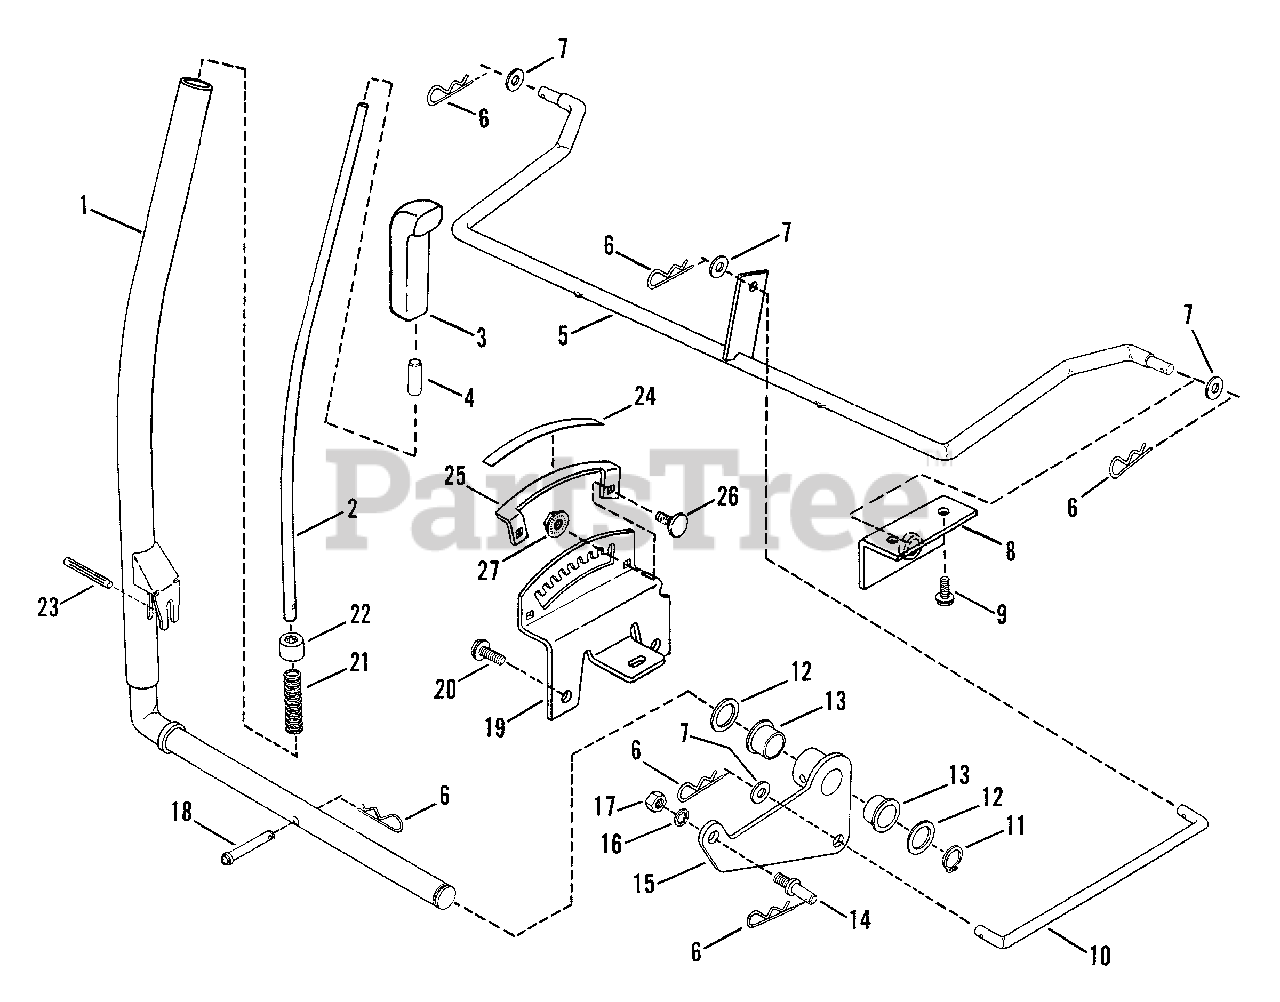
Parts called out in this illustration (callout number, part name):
1	ARM, Implement Lift Lever
2	ROD, Lift Lever
3	GRIP, Lift Lever
4	CAP, Lift Release
5	ARM, Rear Lift
6	PIN, Hair, 3/32 x 1 1/2"
7	WASHER, 3/8 SAE Flat
8	BRACKET, Hanger
9	SCREW, 5/16-18 x 5/8" H.W.H.S.T.
10	LIFT-ROD
11	RING, Retaining
12	WASHER, Lift Lever
13	BEARING, Lift Lever
14	STUD
15	PIVOT ASSEMBLY, Lift Lever
16	WASHER, 3/8 Int. Tooth Lock
17	NUT, 3/8-24 Hex
18	PIN, Clevis, 5/16 x 1 11/16"
19	QUADRANT, Lift Lever
20	SCREW, 5/16-18 x 5/8" Self-Tapping
21	SPRING, Lift Lever
22	PLUG, Lift Lever
23	GROOVE-PIN, 3/16 x 2"
24	DECAL, Cut Height
25	INDICATOR, Cut Height
26	BOLT, 1/4-20 x 5/8" Flt. Hd. Carr.
27	NUT, 1/4-20 Hex Flg. Lock
